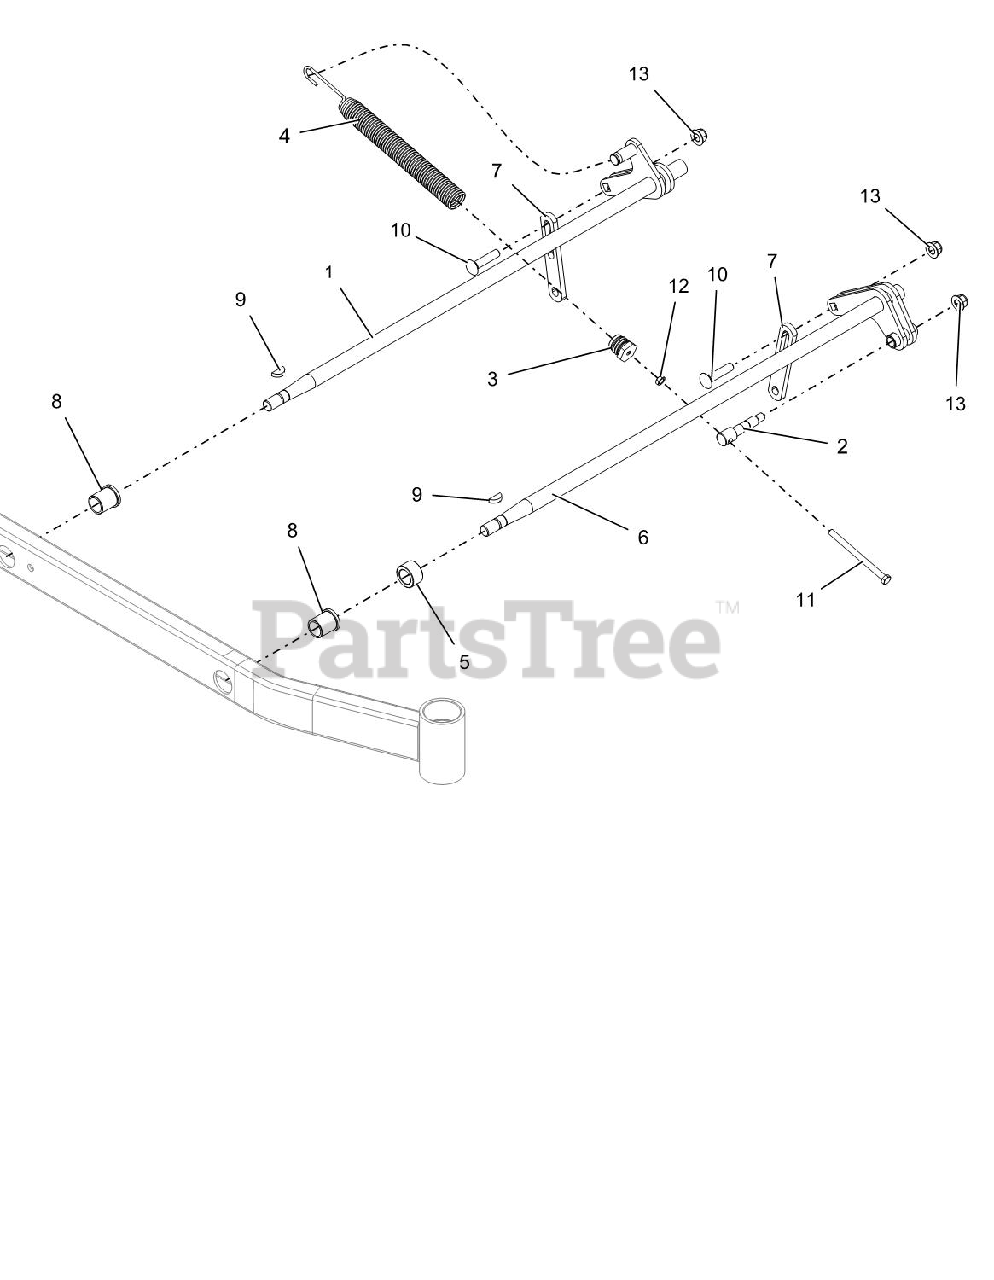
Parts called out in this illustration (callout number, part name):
1	REAR LH DECK LIFT ARM WMT -LF
2	TRUNION, DECK LIFT SPRING
3	PLUG, SPRING
4	SPRING, DECK LIFT
5	SPACER, 1.500 X 1.000 X .880
6	FRONT LH DECK LIFT ARM WMT -LF
7	LINK-DECK LIFT - LONG
8	BSHG-FLG 1.00X1.25X1.50X1.50
9	KEY-WDRF .25X1.00 HRD #15
10	BLT-RDHDSQNK .50-13X2.25 G5YZ
11	BLT-HEX .38-16X5.00 GR5 FTH YZ
12	NUT-HEX-JAM .375-16 YWZC
13	NUT-LK-NYL-FLG .50-13 YWZC
